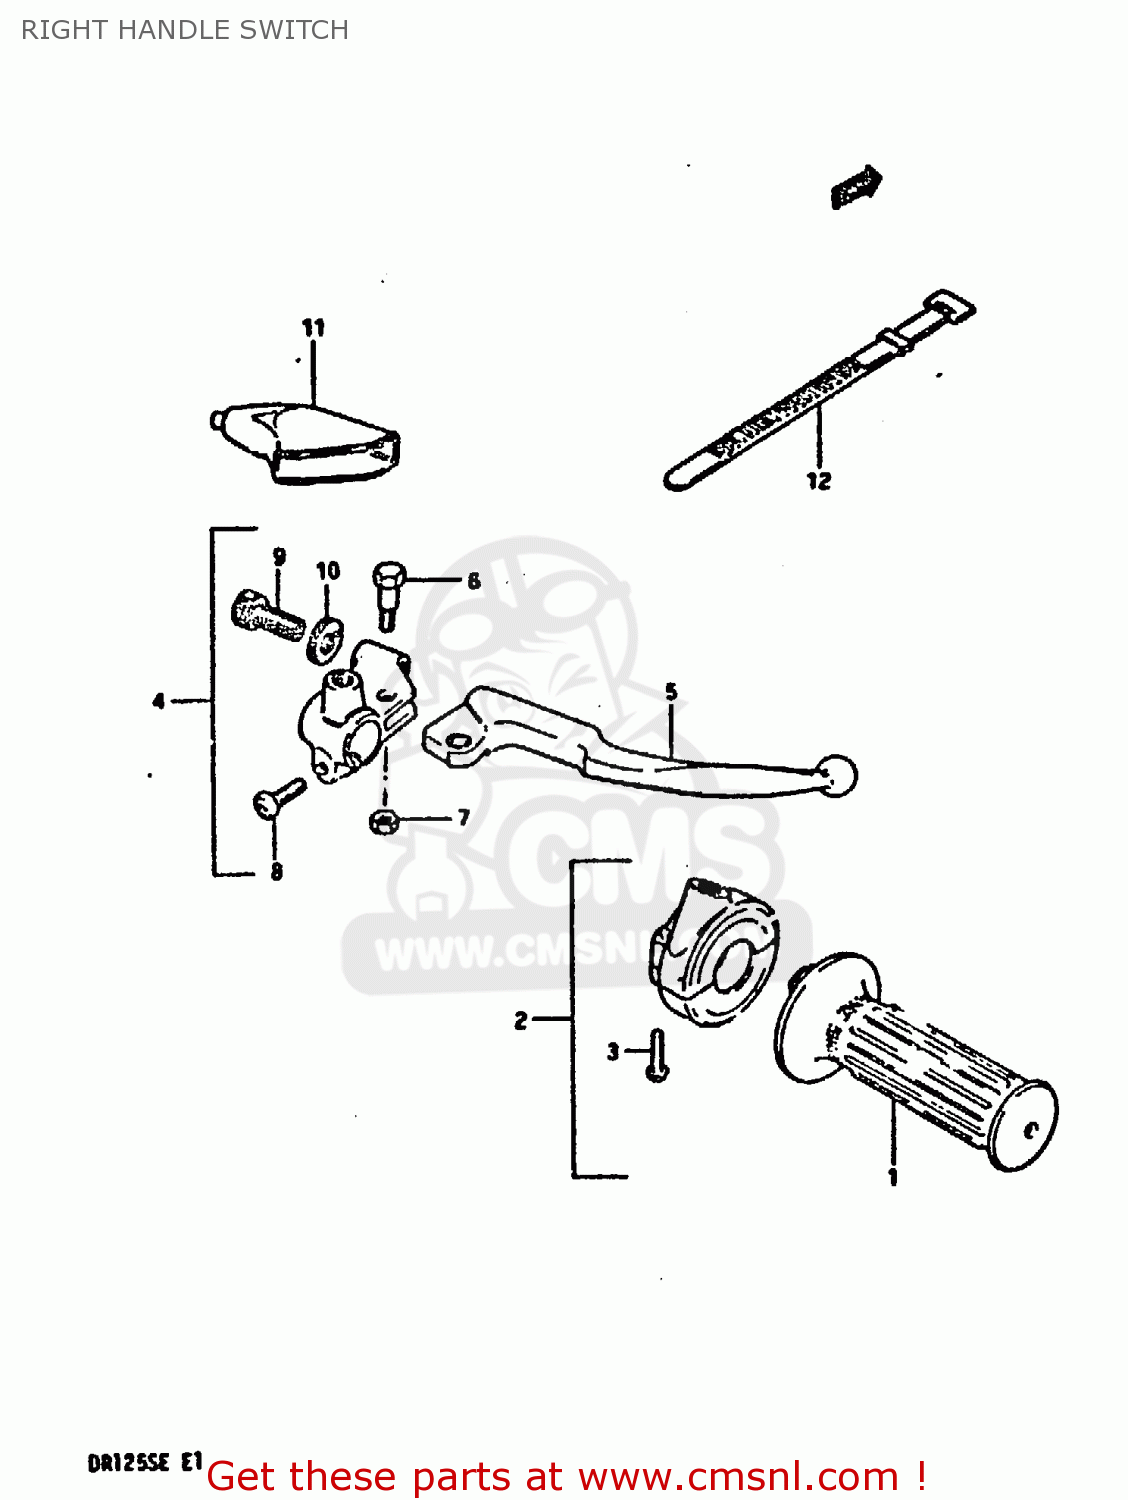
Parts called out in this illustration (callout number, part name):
1	GRIP,THROTTLE
2	CASE ASSY,THROTTLE
3	SCREW 5X20
4	LEVER ASSEMBLY,BRAKE
5	LEVER,BRAKE
6	BOLT,LEVER
7	NUT 6MM
8	SCREW
9	ADJUSTER,CABLE
10	NUT,CABLE ADJUSTER
11	COVER,CLUTCH LEVER
12	CLAMP(L:120)
